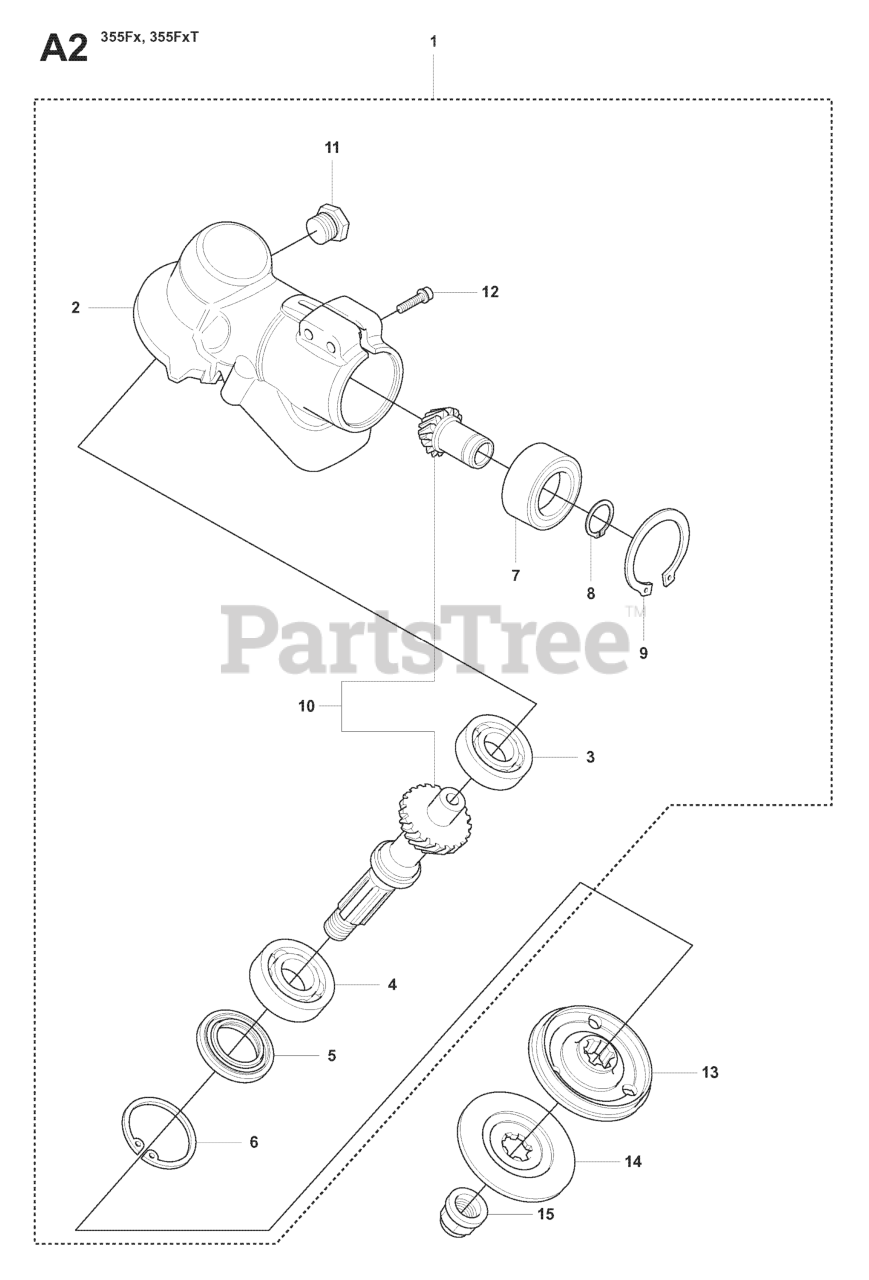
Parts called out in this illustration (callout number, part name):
1	RP BEVEL GEAR
2	%GEAR HOUSING
3	BALL BEARING
4	BALL BEARING
6	RETAINING RING SGH 35
8	RETAINING RING SGA 15
9	RETAINING RING
10	BEVEL GEAR
14	SUPPORT FLANGE
15	BLADE NUT
